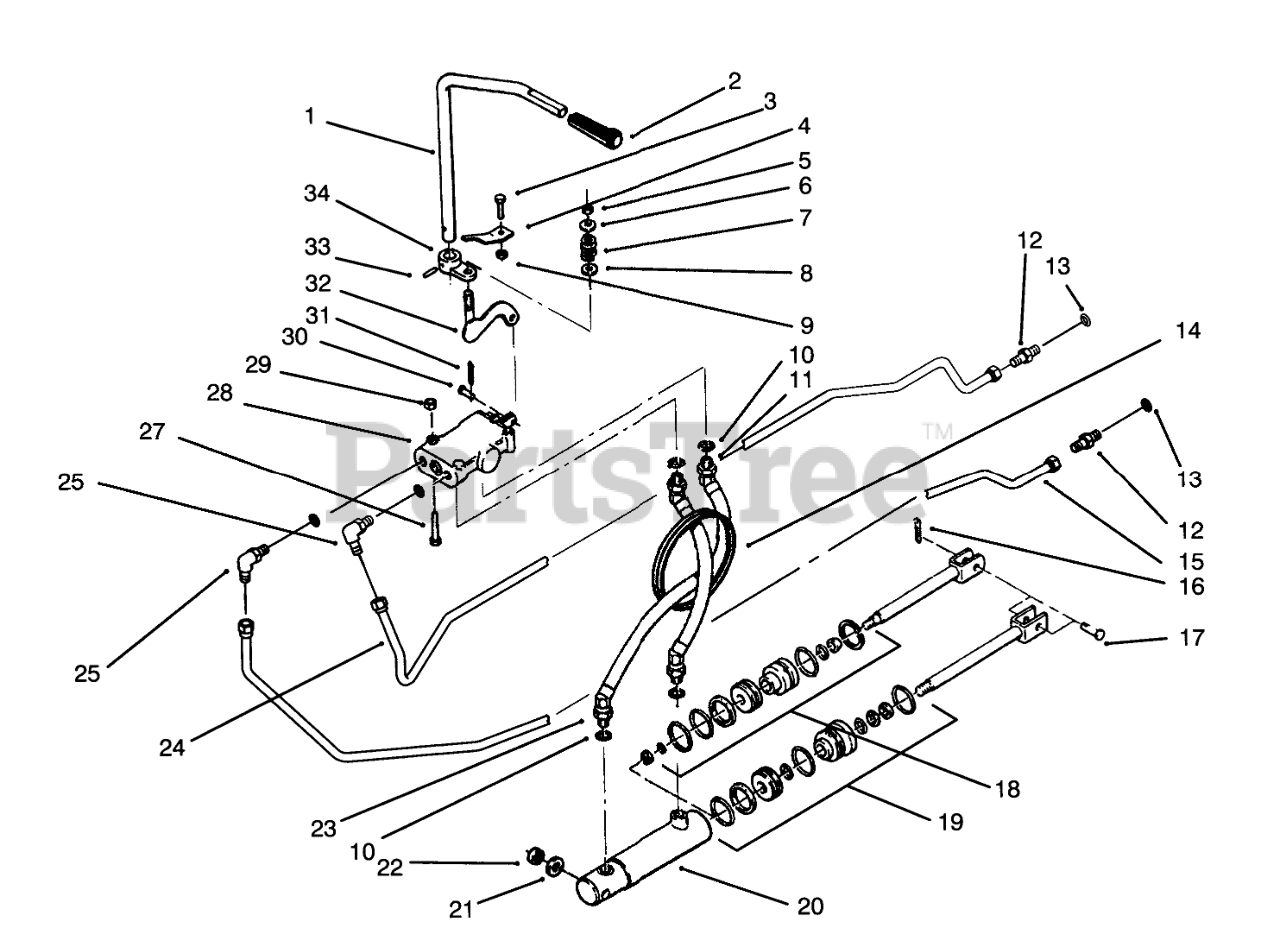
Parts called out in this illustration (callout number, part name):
1	ROD-LIFT CONTROL
2	KNOB-HYDRAULIC LIFT
3	SCREW-HH
4	BRACKET-CONTROL R B
5	NUT-LOCK, NI
7	SPRING
8	SCREW-HH
9	NUT-LOCK, NI
10	O RING
11	Hose ASM-Hydraulic
12	Fitting-Straight Adapter (Incl. Ref. #13)
13	0-Ring
14	GROMMET
15	TUBE-HYD PRESSURE
16	PIN-COTTER
17	CLEVIS PIN
18	S/A O-RING&GASKET AS
19	S/A 108872 HYD CYL
20	Cylinder-Hydraulic (Incl. Ref.# 18-19)
21	SPACER-WORM SHAFT
22	WASHER
23	Hose ASM-Hydraulic
24	TUBE-HYD RETURN
25	Fitting-90deg. (Incl. Ref. #13)
27	SCREW-HH
28	Valve-Hydraulic (Incl.Ref.# 30-31)
29	NUT-LOCK, NI
30	Pin
31	Cotter Pin
32	WLDMT-LIFT BAR
34	ARM-CONTROL
